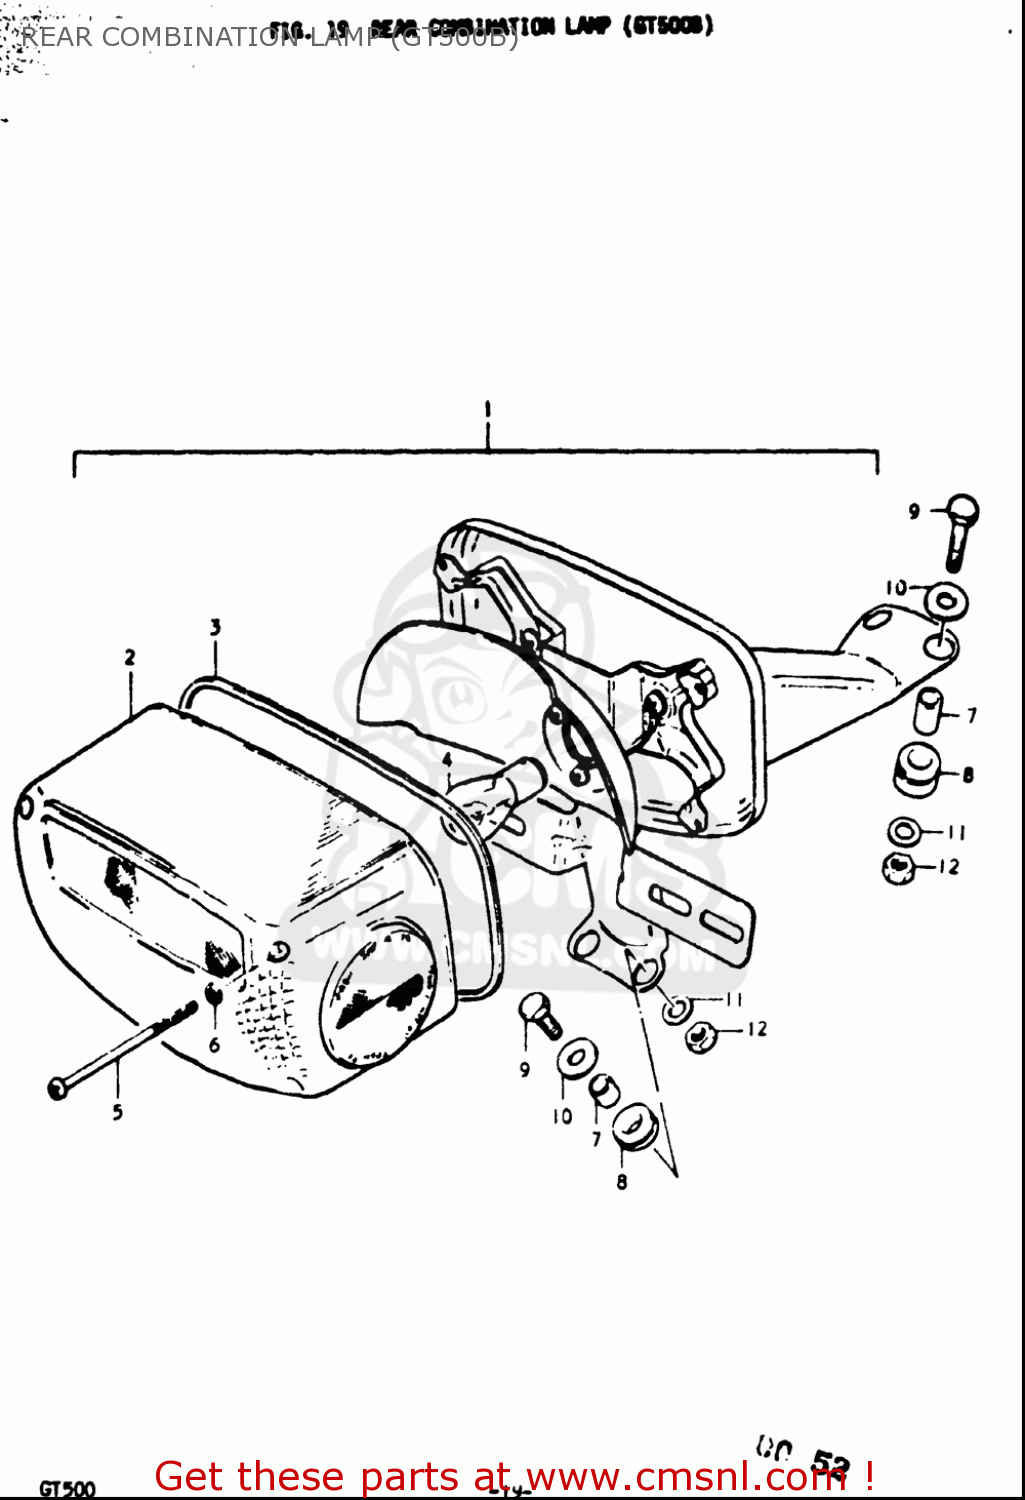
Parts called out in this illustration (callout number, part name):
2	LENS
3	GASKET (NAS)
4	BULB(12V23W)
6	GASKET (NAS)
7	SPACER
8	CUSHION
9	BOLT
10	WASHER(6.5X20X1.2)
11	WASHER
12	NUT
